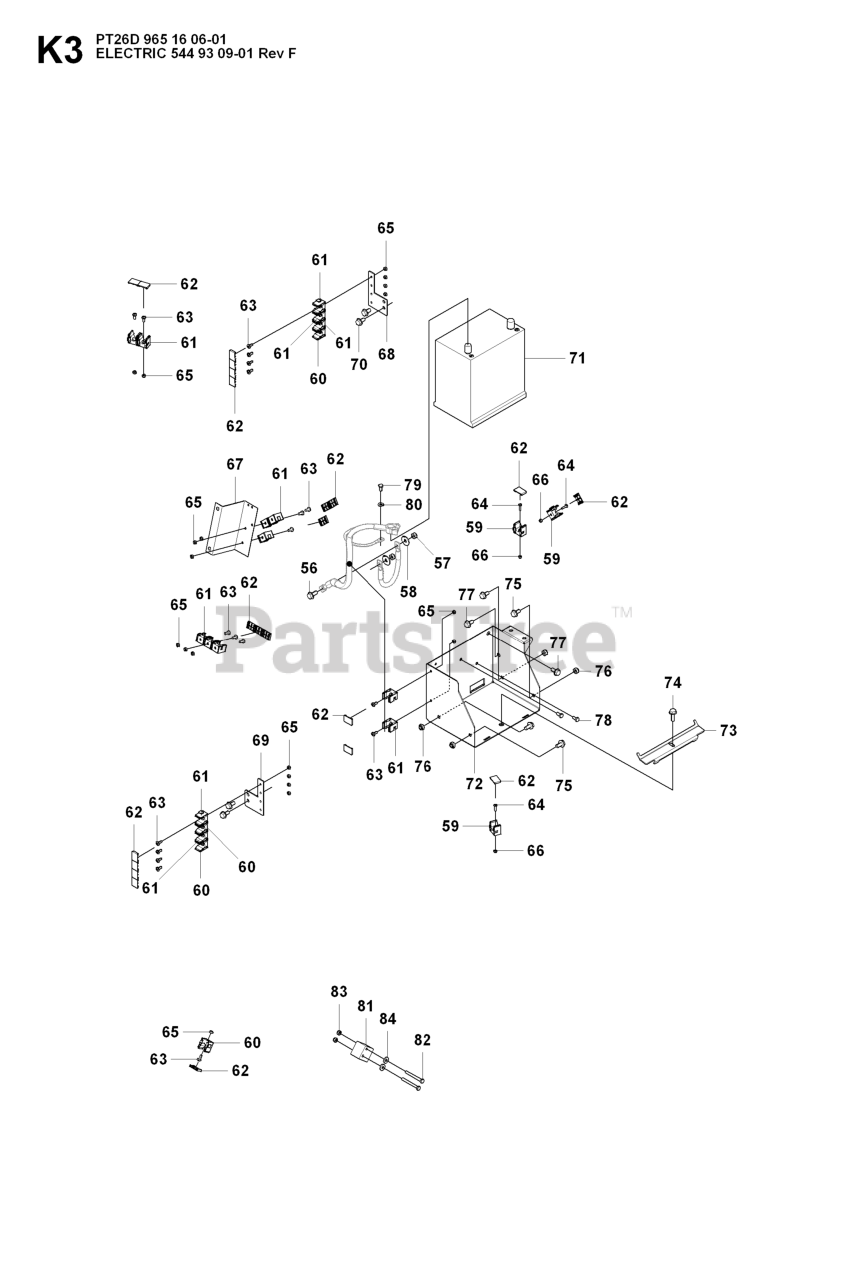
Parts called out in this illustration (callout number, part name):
8	SCREW EHHFM
11	SCREW M6S 5X20
13	LOCKNUT M5
17	COVER FUSE HOLDER
33	THROTTLE HANDLE ASSY
49	WIRING FUSE POWER
55	FUSE HOLDER
57	LOCKNUT M8
58	WASHER BRB 8.4X17
65	LOCKNUT M5
74	BOLT
76	LOCKNUT M8
80	WASHER
81	BRACKET SENSOR LIFT
82	SCREW M6X55
83	LOCKNUT M6
